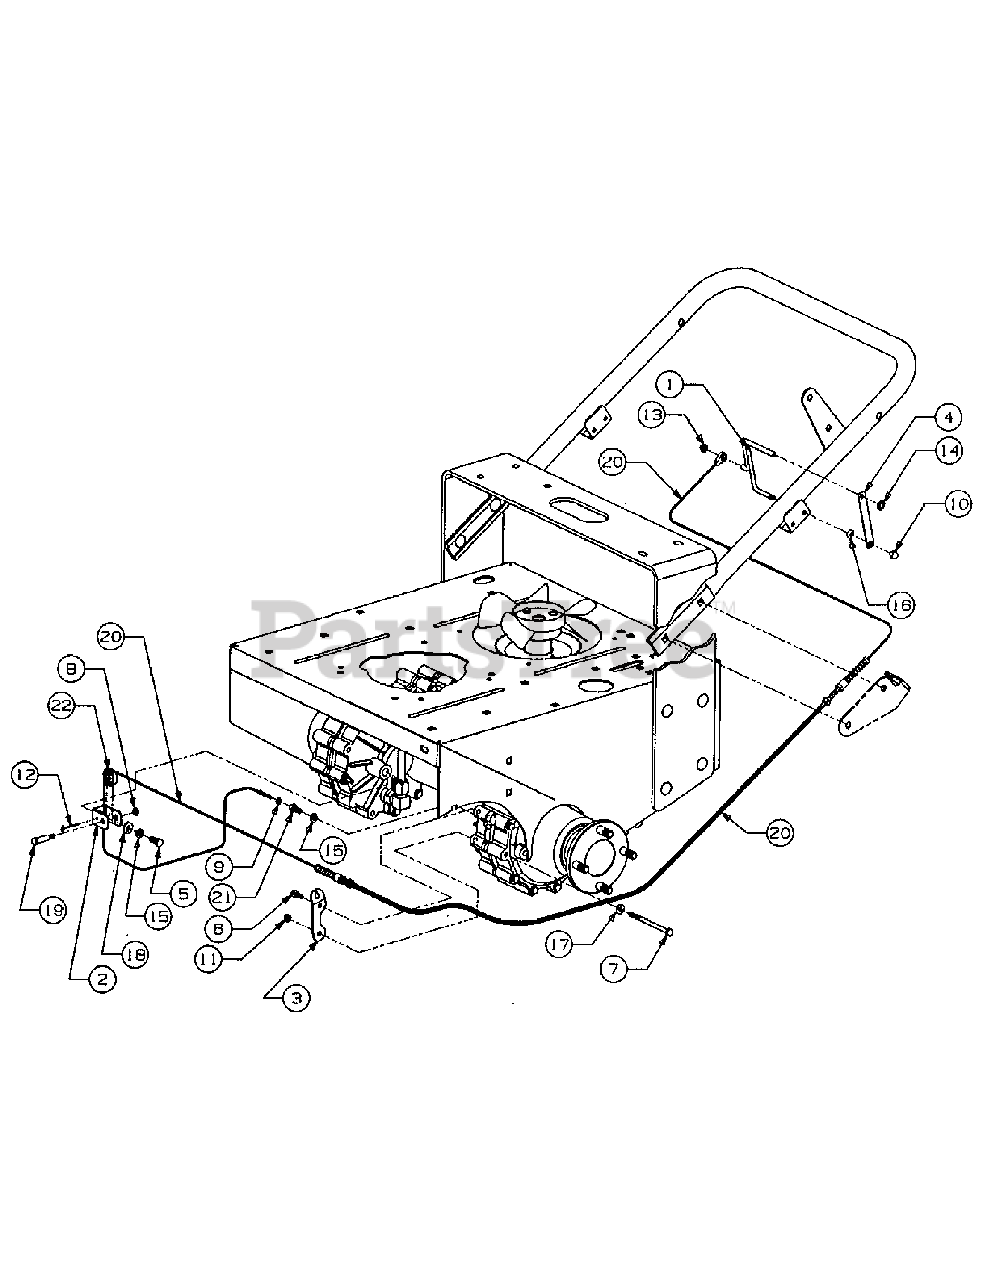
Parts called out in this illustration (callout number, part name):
1	Lever,Drive Wheel release
2	Bracket, Pulley
3	Plate, Release Cable
4	Plate Retainer
4	Graphic, Transaxle Release
5	Screw, Hex Cap, 5/16-24 x .75 Gr 5
6	Screw, Hex Wash Hd Tapp, 1/4-20 x .75
7	Screw, Hex Cap, 1/4-20 x 4.0
8	Nut, Hex Top Lock, 1/4-20
9	Nut, Hex #10-32
10	Nut, Hex Lock Stop, 1/4-28
11	Nut, Hex Top Lock, 1/4-20 Gr 5
12	Pin, Cotter, 5/32 Dia x 1.25
13	Nut, Cap Speed, .312 Stud
14	Nut, Push-On Speed, 5/16
15	Washer, Lock, 5/16
16	Washer, Spring
17	Washer, Flat .25 x .62
18	Washer, Flat .312 x .750 x .119 Thk
19	Bolt, Pulley
20	Cable, Drive Wheel Release
21	Bolt, Cable Adapter
22	Pulley Cable
